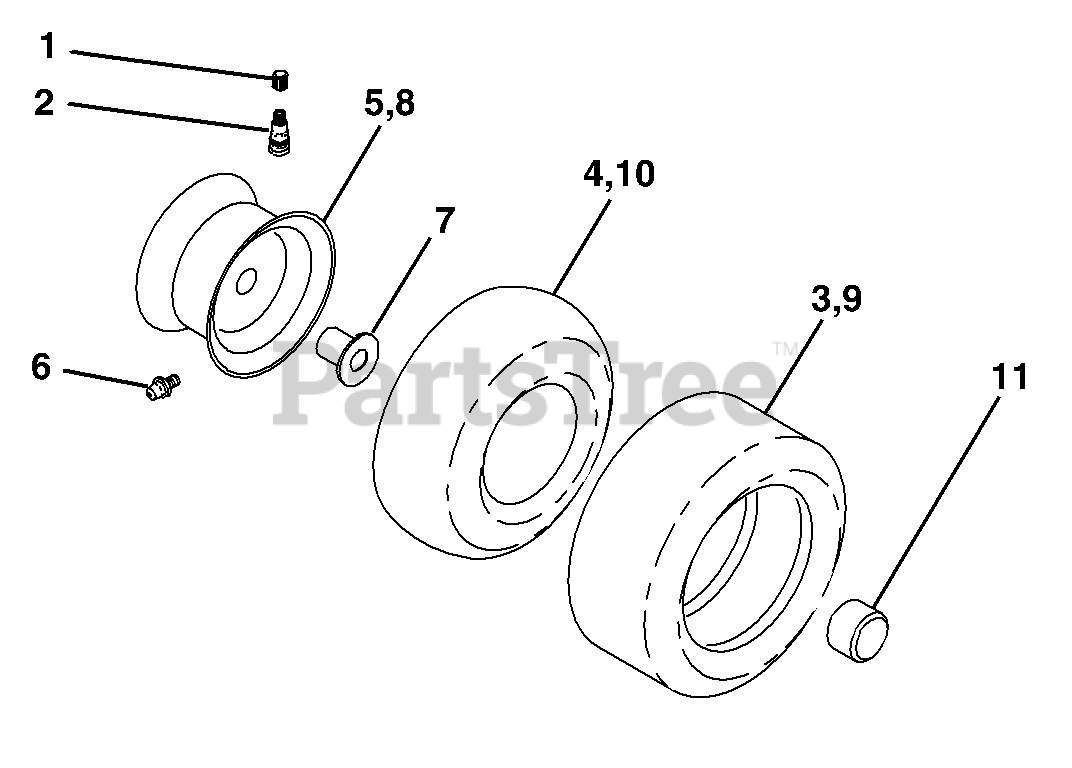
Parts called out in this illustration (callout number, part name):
1	Cap, Tire valve
2	Stem, Valve
3	Tire, Front
4	Tube, Front (Service item only)
5	Rim assembly, 6"front
6	Fitting, Grease (Front wheel only)
7	Bearing, Flange (Front wheel only)
8	Rim assembly, 8" rear
9	Tire, Rear
10	Tube, Rear (Service item only)
11	Cap, Hub Axle
